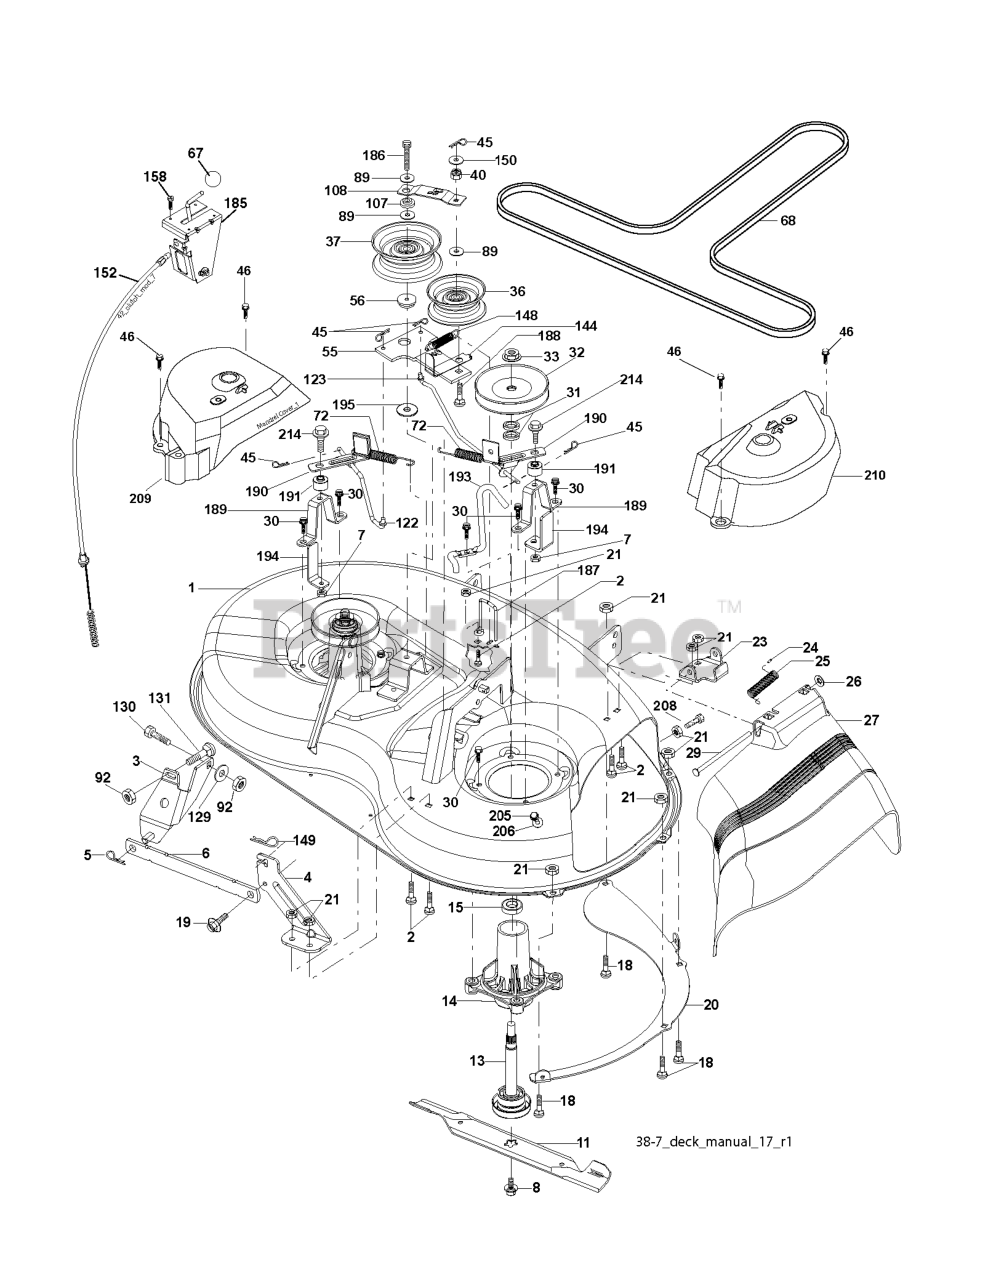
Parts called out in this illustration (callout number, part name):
1	DECK SVCX1 38/94 192556X431
2	RP BOLT 5/16-18 X3/4 ZN/YEL GR
3	BRKT ASM SWAY BAR
4	BRACKET DECK SWAY BAR 38"/42"
5	RETAINER-SPRNG RB
6	BAR SWAY DECK
7	NUT.71038.31-18.HEX.NYLOCK
8	BOLT.WASHER.ASM.7/16-2
11	BLADE 38" PREMIUM
13	SHAFT.ASM.MDRL.N/GREASE.38
14	RP.HOUSING.MANDREL.4PT.
18	BOLT
19	BOLT SHD 5/16-18
20	BAFFLE.VORTEX.FRONT.38"
21	LOCKNUT
23	BRKT.DEFLECTOR.38"2005+
24	CAP-SLEEVE LT
25	SPRING.TORSION.DEFLECT
26	NUT PUSH M
27	SHIELD ASM.DFLCTR MWR.38-7"BLK
29	ROD.HINGE
30	SCREW, WASHER HEAD
31	WASHER.SPACER.MANDREL
32	PULLEY MANDREL
33	NUT.FLANGE.LOCK.TOP
36	FLAT IDLER PULLEY
37	PULLEY.IDLER.FLAT.UNPLATED
45	RETAINER M
46	SCREW.1/4-20X5/8
56	SPACER.RETAINER.MOWER
67	KNOB T (3/8 HOLE)
68	V-BELT.MOWER.38"2005+
72	SPRING.BRAKE.RETURN.38"
89	WASHER
107	SPACER.IDLER.ARM
108	STIFFENER.IDLER.ARM
122	LINK.BRAKE.38"LEFT.2007
123	LINK.BRAKE.38"RIGHT
144	KEEPER BELT
148	IDLER RETURN SPRING
149	SPRING.RETAINER.YELLOW.ZINC
152	CABLE.CLUTCH.38".SERVICE
158	SCREW
185	HEAD ASM. CABLE CLUTCH
186	SCREW.HXWSH.3/8
187	KEEPER BELT
188	BOLT, CARRIAGE IDLER
189	STAND, BRAKE
190	ARM, BRAKE
191	BRAKE.SPACER.38".DECK
193	KEEPER BELT RH MANDREL
194	GUARD BRAKE
195	WASHER 12/32X2X10GA
205	SCREW
208	SCREW 3/8-16X1/2
214	BOLT/WASHER ASM 5/16-18
